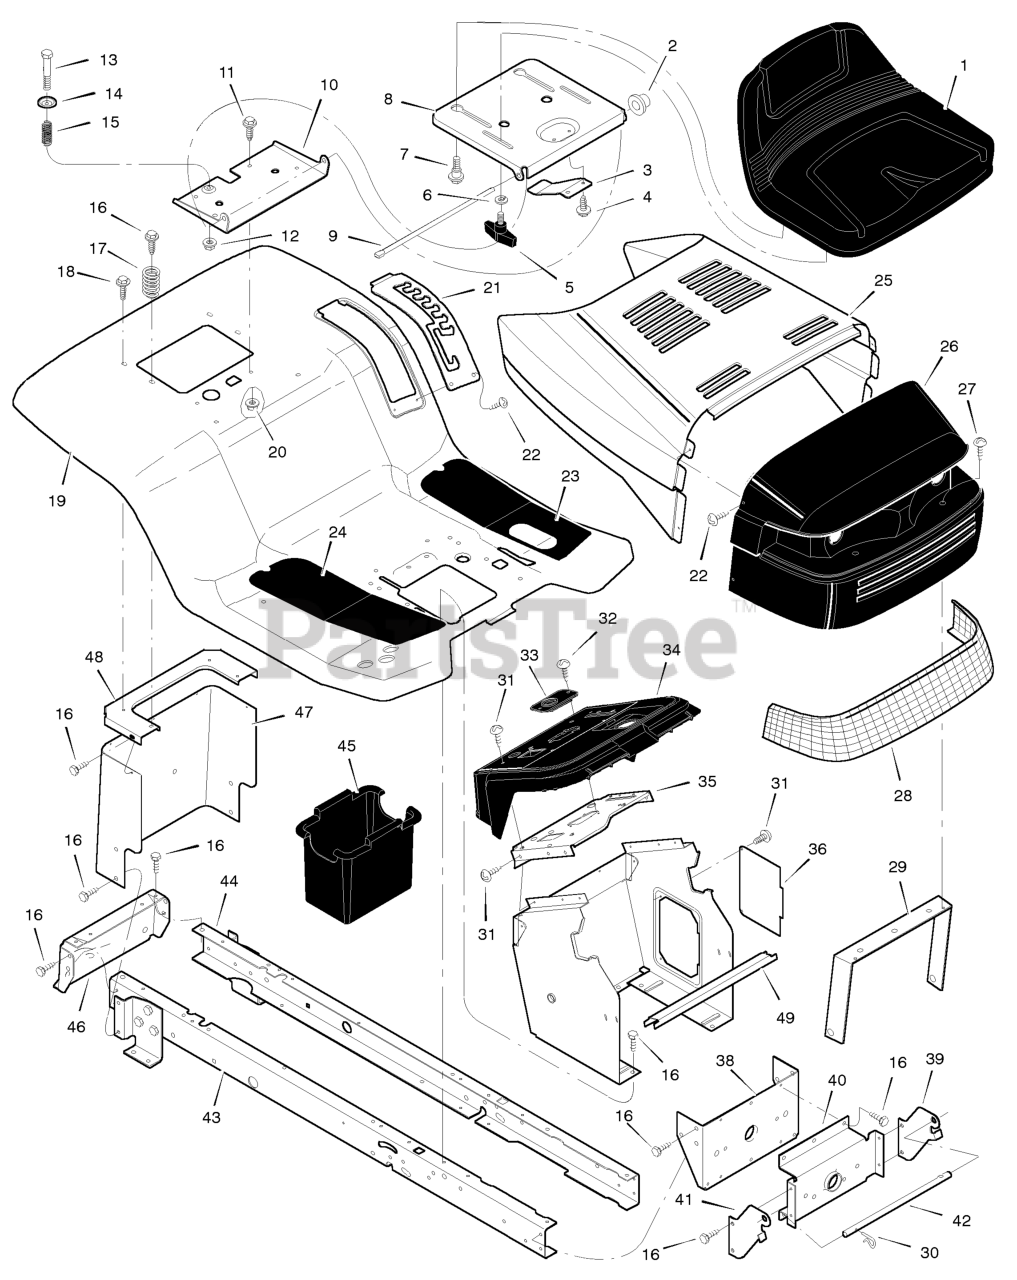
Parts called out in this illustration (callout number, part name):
2	Cap, Push On
5	Bolt, Wing
6	Washer
7	Bolt, Shoulder
8	Support, Seat
9	Rod, Pivot
10	Bracket, Pivot
11	Bolt
13	Bolt, Shoulder
15	Spring
19	Deck, Seat
20	Nut
21	Plate, Index
23	Mat, Left
24	Mat, Right
26	Grille Assembly
29	Brace, Grille
30	Pin, Hair
31	Screw
33	Bearing, Steering
35	Plate, Dash
36	Panel, Access
37	Support, Dash
38	Bracket, Rear Hanger
39	Support, Left Grille
40	Axle, Hanger
41	Support, Right Grille
42	Rod, Pivot
43	Frame, Right
44	Frame, Left
45	Container, Battery
46	Plate, Hitch
47	Panel, Rear
48	Cover, Level Adjustment
